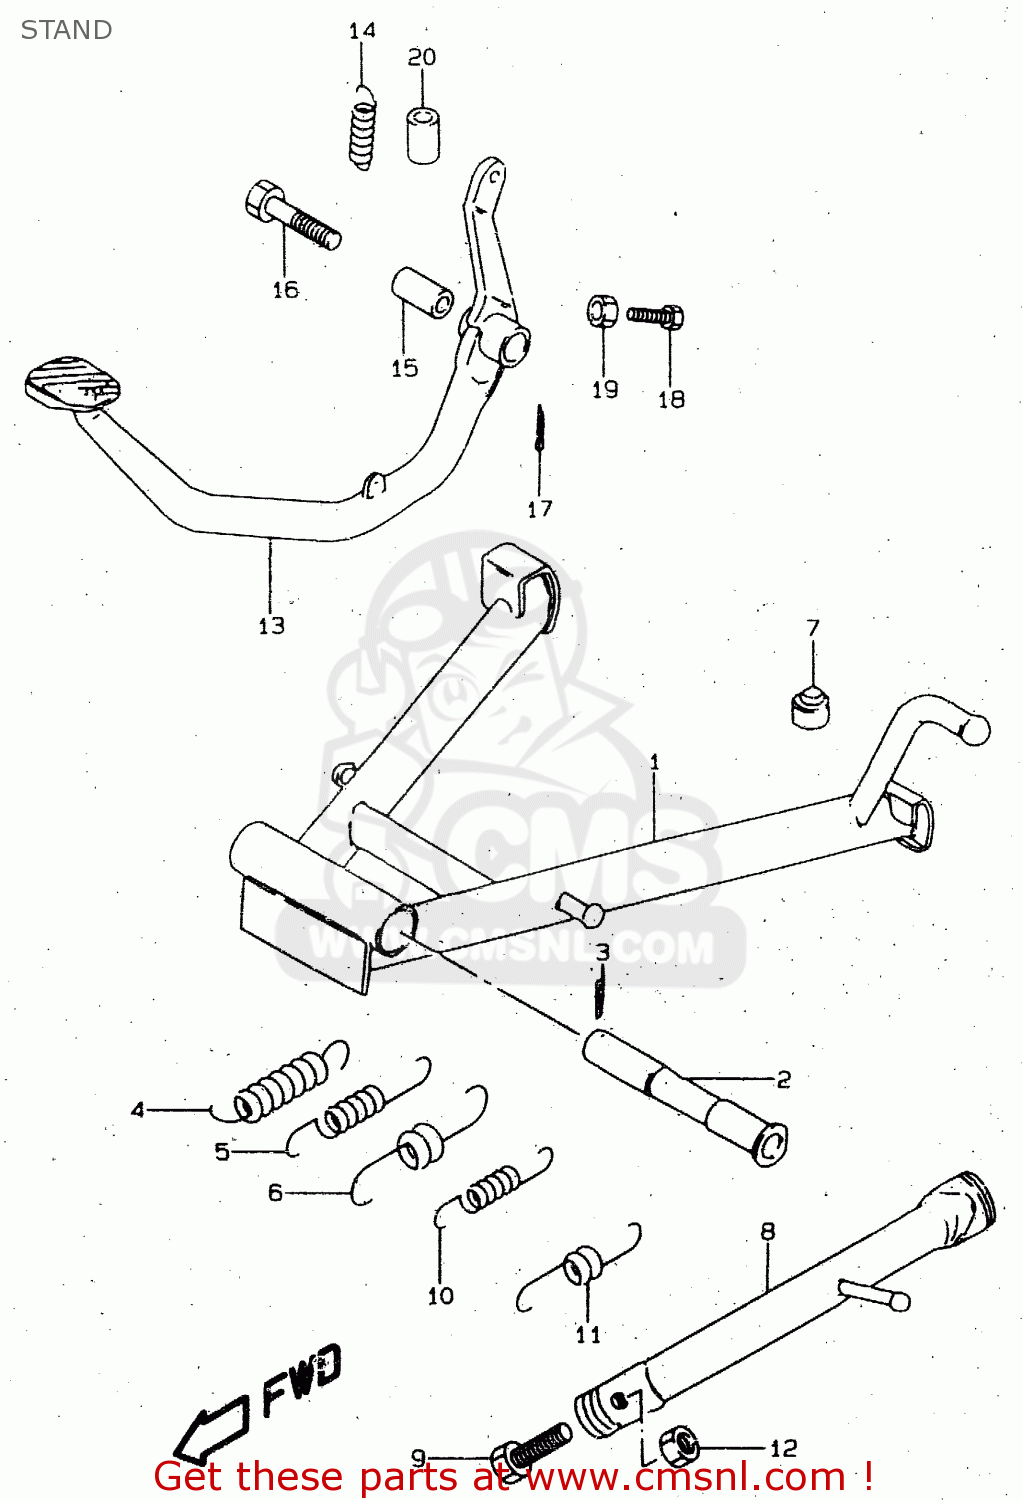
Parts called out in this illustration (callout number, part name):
1	STAND,CTR
2	SHAFT,CTR STAND
3	COTTER PIN
4	SPRING
5	SPRING
6	SPRING
7	CUSHION
8	STAND,PROP
9	BOLT(10X30)
10	SPRING
11	SPRING
12	NUT
13	PEDAL,BRAKE
14	SPRING
15	SPACER,BRAKE PEDAL BOSS
16	BOLT(10X52)
17	PIN 20X20
18	BOLT(6X23)
19	NUT 6MM
20	TUBE,BRAKE SPRING GUIDE
